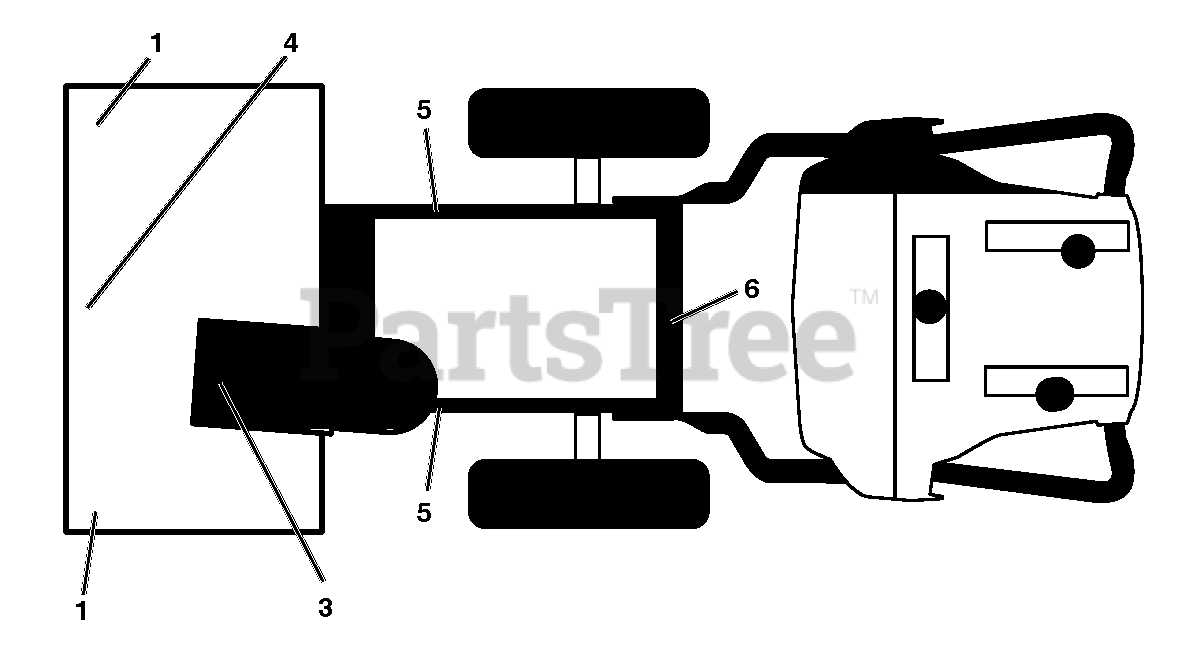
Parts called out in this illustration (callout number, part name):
1	DECAL.AUGER.SAFETY.
3	DECAL.CHUTE.SAFETY.
4	DECAL.AUGER."
5	DECAL.BELT.GUARD.
6	DECAL.NOISE.LEVEL.105DB/CE.EAC
